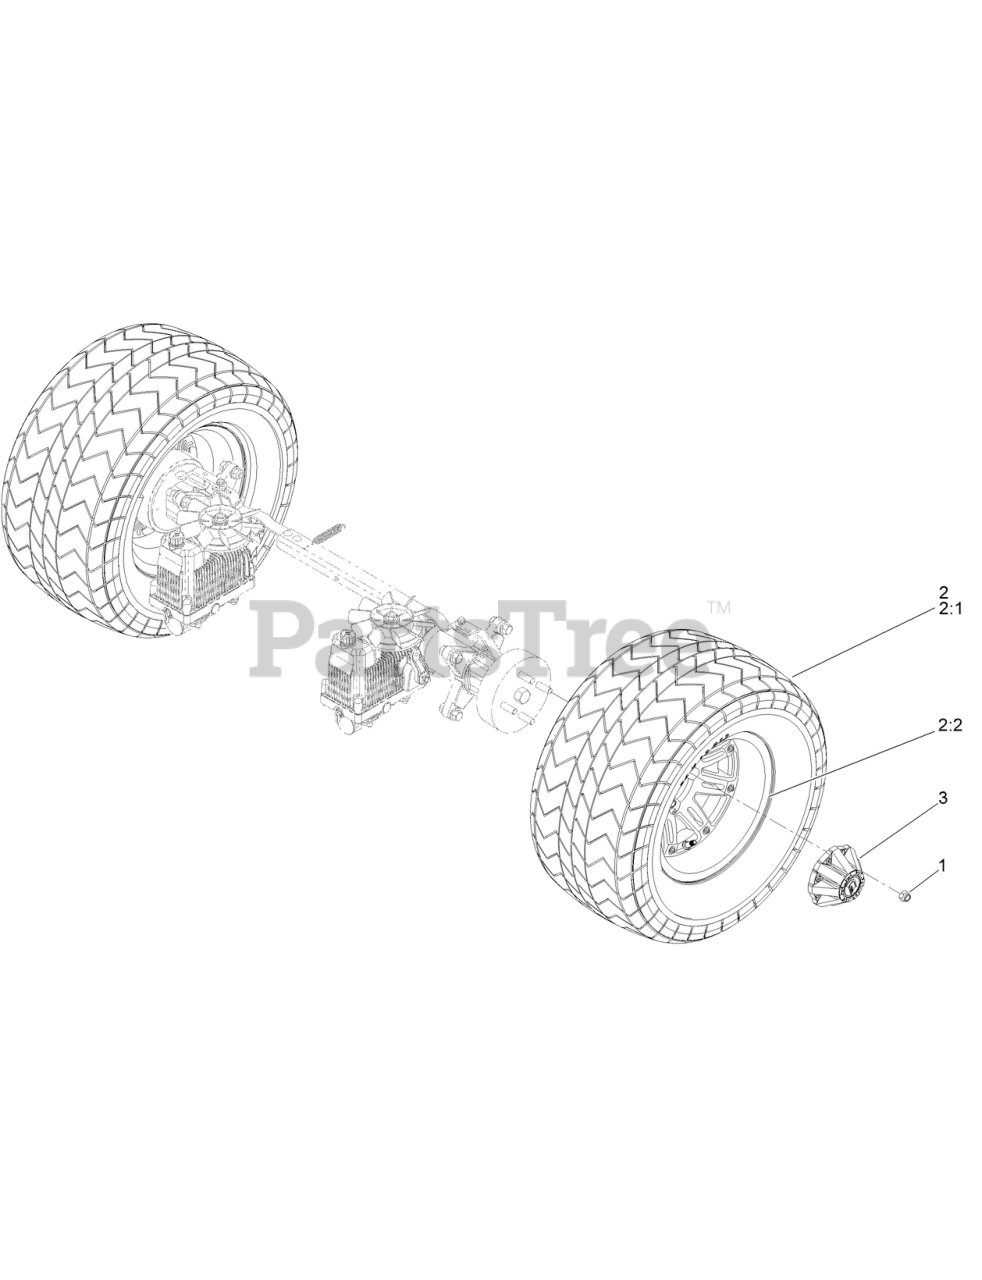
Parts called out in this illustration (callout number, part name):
1	1/2-20 LUGNUT
2	WHEEL AND TIRE ASM
2:1	24X 12 X 12 SOFT RIDE RADIAL TIRE ONLY
3	CENTER CAP- SPARTAN
